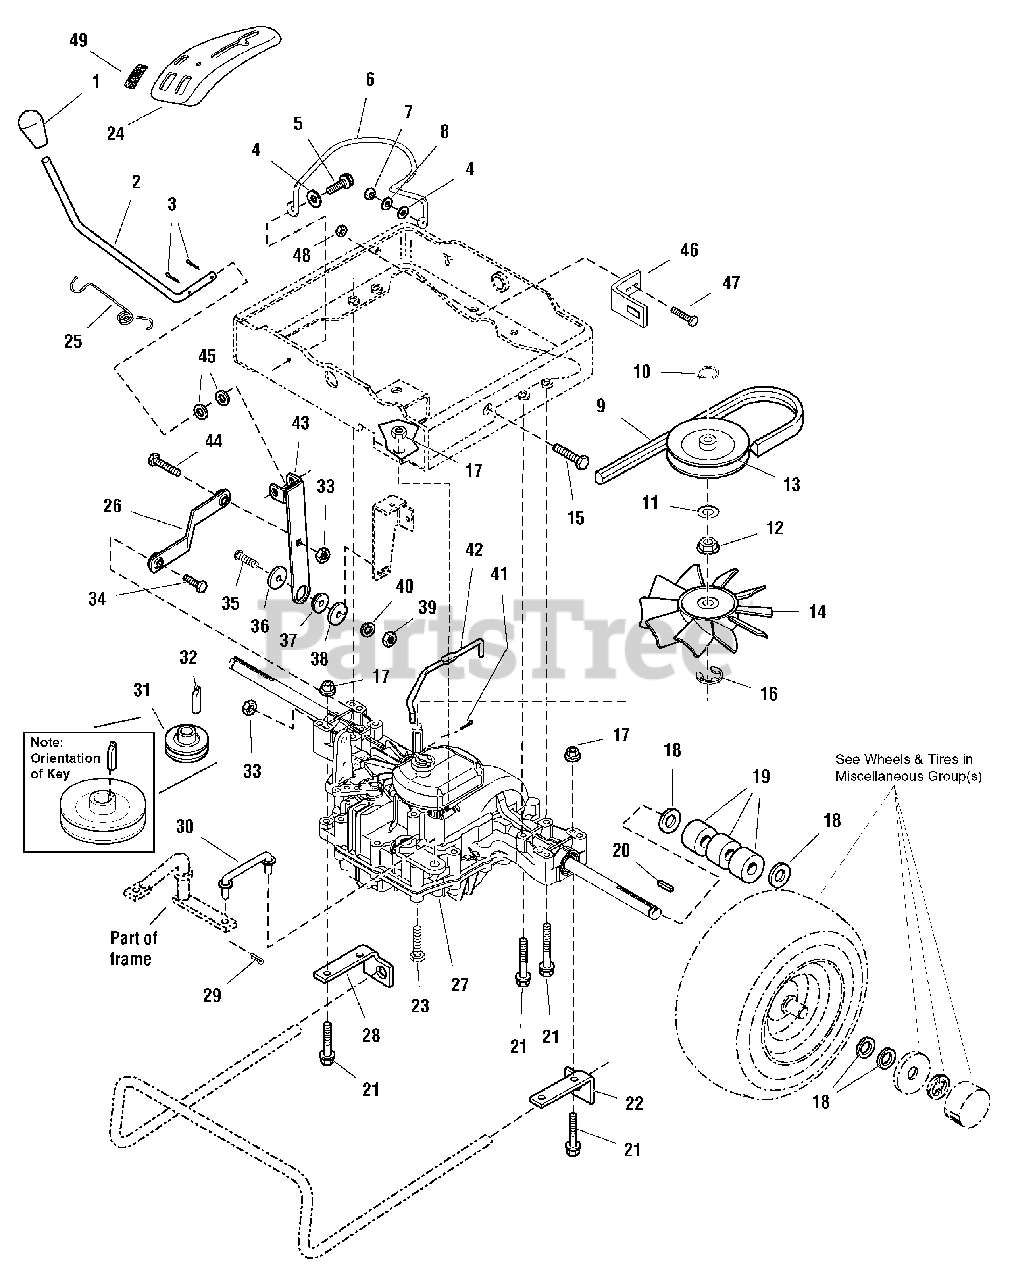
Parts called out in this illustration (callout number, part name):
3	PIN, Cotter
5	SCREW, Hex Washer Head Taptite, 5/16-18 x 3/4
7	NUT, Hex 5/16-18
8	LOCKWASHER, 5/16
10	SNAP RING
11	LOCKWASHER
12	SPLINE COLLAR
13	PULLEY
14	FAN
15	CAPSCREW, Hex Head, 5/16-18 x 1
16	E RING
17	NUT, Hex Flange Whizlock, 5/16-18
20	KEY
21	CAPSCREW, Hex Head Taptite, 5/16-18 x 2-1/2
22	ANCHOR, Torsion Bar LH
23	CAPSCREW, Hex Head Flange Whizlock, 5/16-18 x 1-3/4
24	POD, Control Pod
26	LINK, Transmission
27	TRANSMISSION ASSEMBLY
28	ANCHOR, Torsion Bar RH
29	PIN, Cotter
31	PULLEY & HUB ASSEMBLY
32	KEY, Hi-Pro
33	NUT, Hex Two Way Lock, 5/16-18
34	CAPSCREW, Hex Head, 5/16-18 x 1-1/4
35	CARRIAGE BOLT, 3/8-16 x 1-1/4
36	WASHER
39	NUT, Hex, 3/8-16
40	LOCKWASHER, 3/8
41	PIN, Cotter
43	LEVER & CLEVIS ASSEMBLY
44	CARRIAGE BOLT, 5/16-18 x 1
46	BRACKET, Switch
47	CARRIAGE BOLT, 1/4-20 X 5/8
48	NUT, Flange, Nylon 1/4-20
